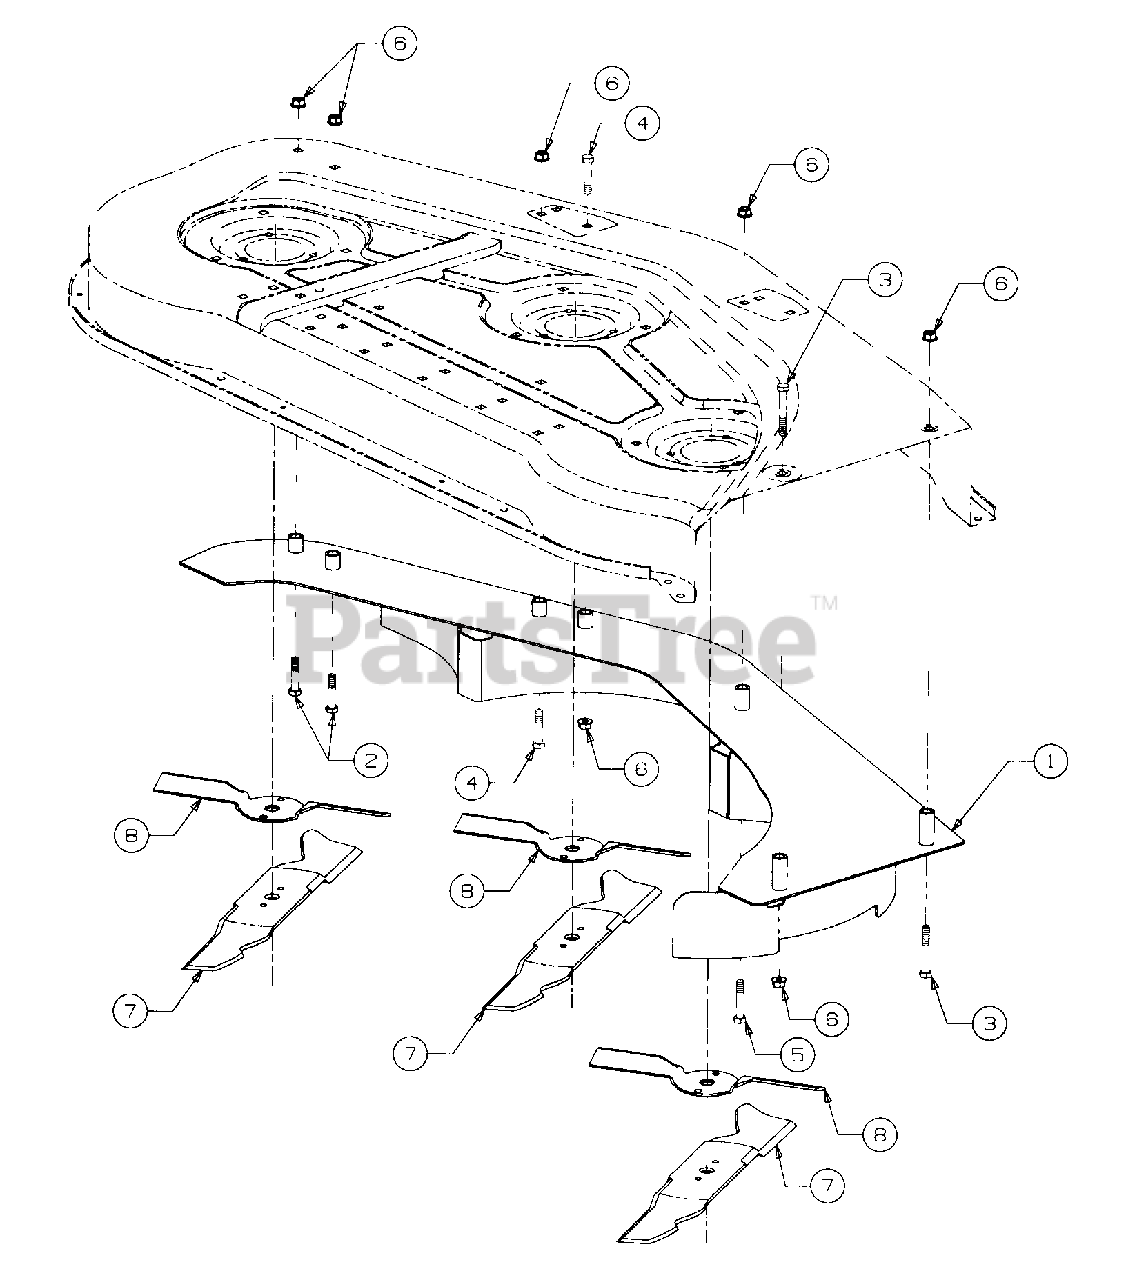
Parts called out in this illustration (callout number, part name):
3	Screw, Hex Cap, 3/8-16 X 2.50 Lg GR5
4	Screw, Hex Cap, 3/8-16 X 1.75 Lg GR5
5	Screw, Hex Cap, 3/8-16 X 2.0 Lg GR5
6	Nut, Hex Flanged Lock, 3/8-16
7	Blade, Mower, 18.5 Lg
